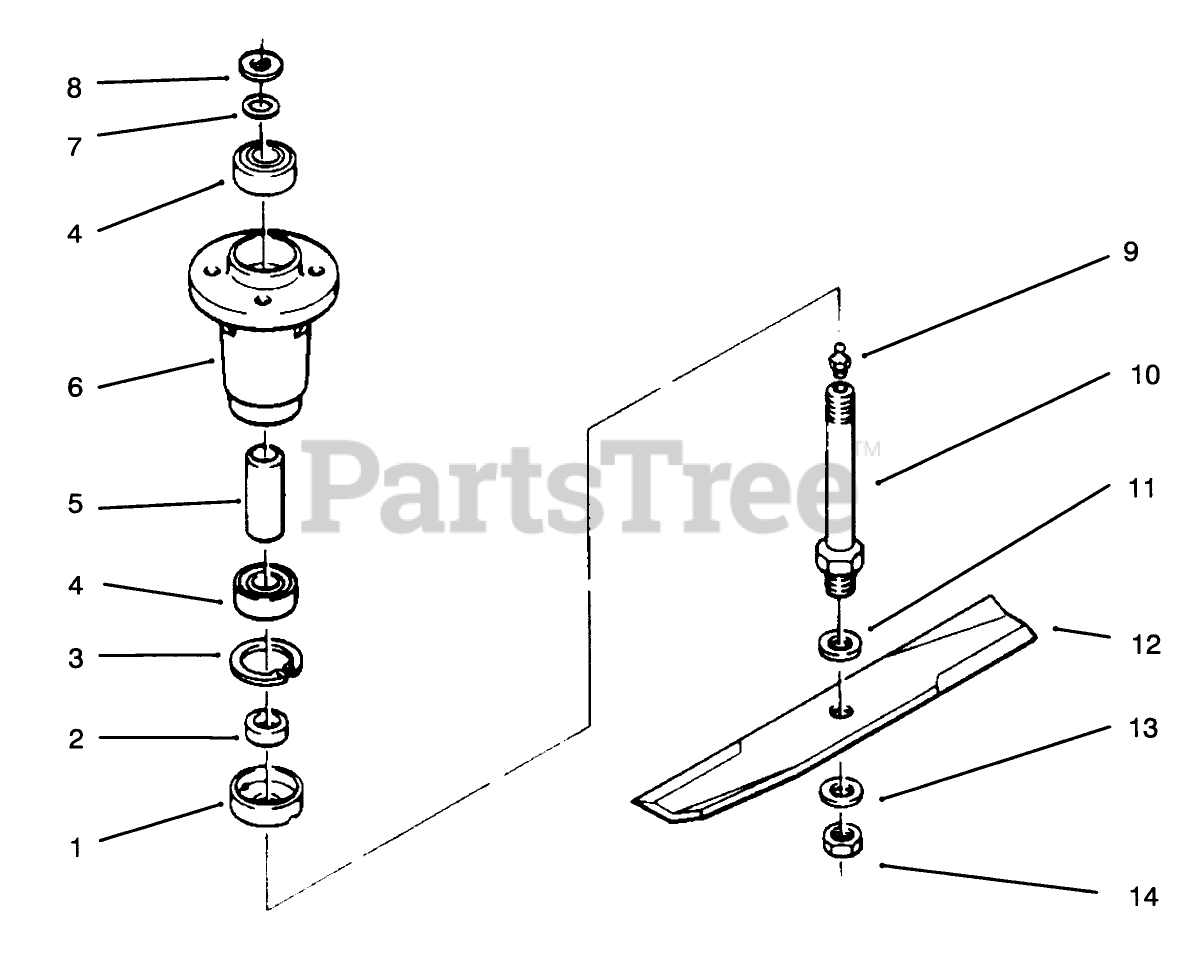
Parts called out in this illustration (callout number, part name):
1	CUP-SPINDLE
2	SPACER-BLADE
3	RING-RETAINING
4	BEARING-BALL
6	HOUSING-SPINDLE
7	O RING
8	Washer
9	FITTING-GREASE
10	SHAFT-SPINDLE
11	Washer
12	S/A BLADE KIT
13	WASHER-FLAT
14	NUT-JAM
